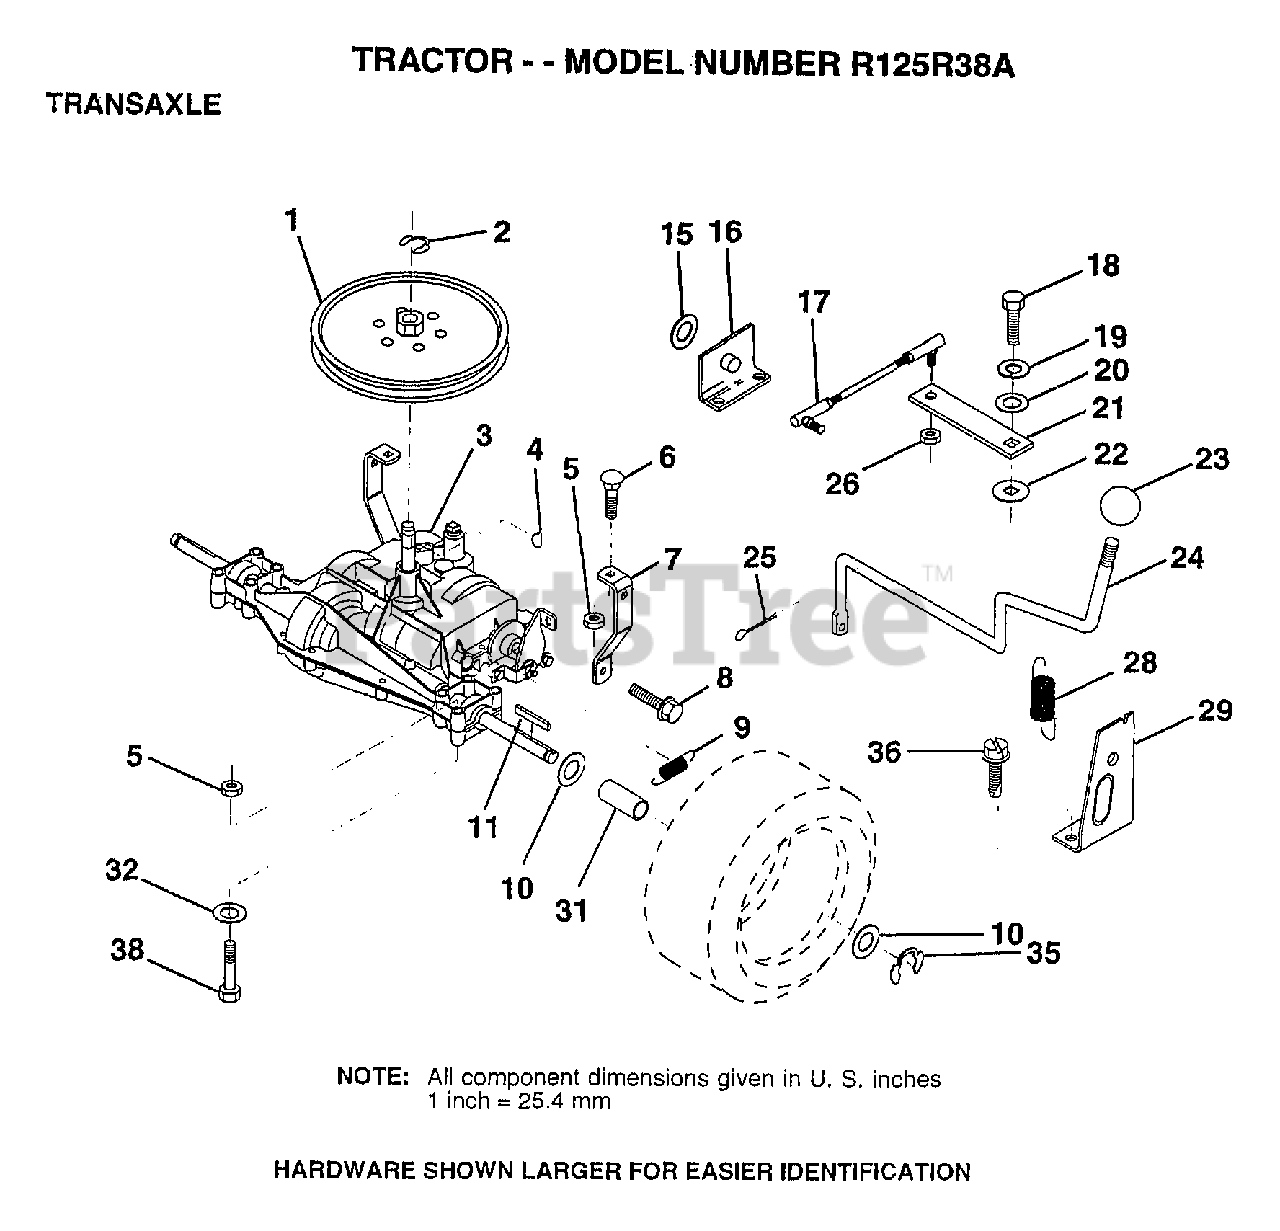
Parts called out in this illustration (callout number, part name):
1	PULLEY
3	TRANSAXLE PEERLESS
6	BOLT
7	"STRAP,TORQUE"
8	SCREW
9	SPRING.BRAKE.RETU
10	WASHER
11	SQUARE KEY
16	SUPPORT HANDLE SHIFT LH
17	LINK SHIFT
18	BOLT.1/4-28.W/PAT
19	LOCKWASHER
20	WASHER LT
22	WASH-SHFT PLT LT
23	KNOB T (1/2-HOLE)
24	"ROD,SHIFT"
25	PIN COTTER 1/8
26	NUT.LOCK.5/16-24
28	"SPRING,EXT"
29	"SUPT,HDLE RH"
31	SPACER AXLE
32	WASHER
35	E-RING LT
36	SCREW
38	BOLT.HX.FLG.5/16
